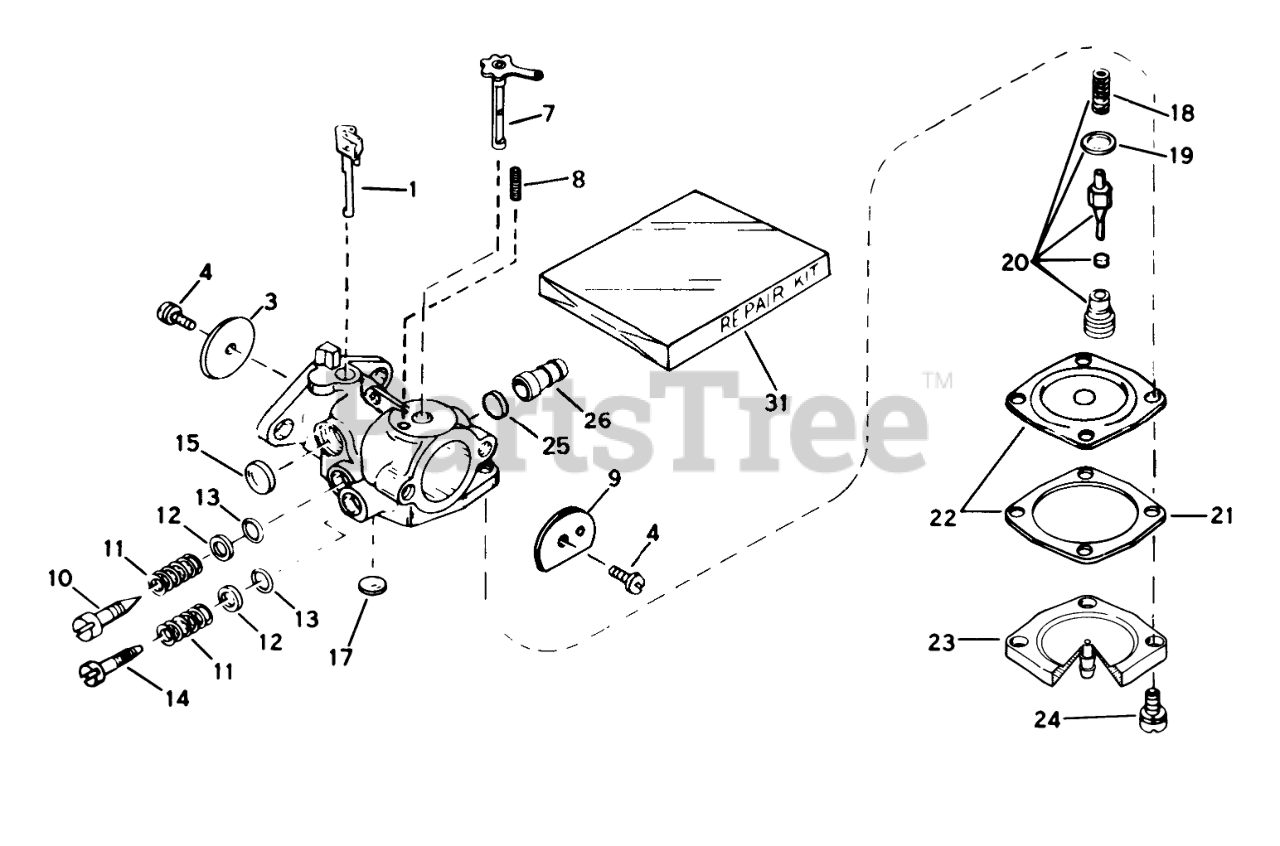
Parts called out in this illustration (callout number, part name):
1	Shaft/Lever-Throttle
3	Shutter-Throttle
4	Screw-Shutter
7	Shaft & Lever Assembly
8	Spring-Positioning, Choke
9	Shutter-Choke
10	Screw-Idle Adjustment
13	"O"Ring
14	Screw Main Adjustment
15	Plug-Welch, Idle Mixture Well
17	Plug Welch
18	Spring-Valve
19	Gasket-Valve Seat
20	Inlet Needle, Seat, Spring & Gasket Assy. (Incl. #18 & 19)
21	Gasket-Diaphragm
22	Diaphragm Assy. (Incl. #21)
23	Cover-Diaphragm
26	Fitting-Fuel
31	Kit-Repair
